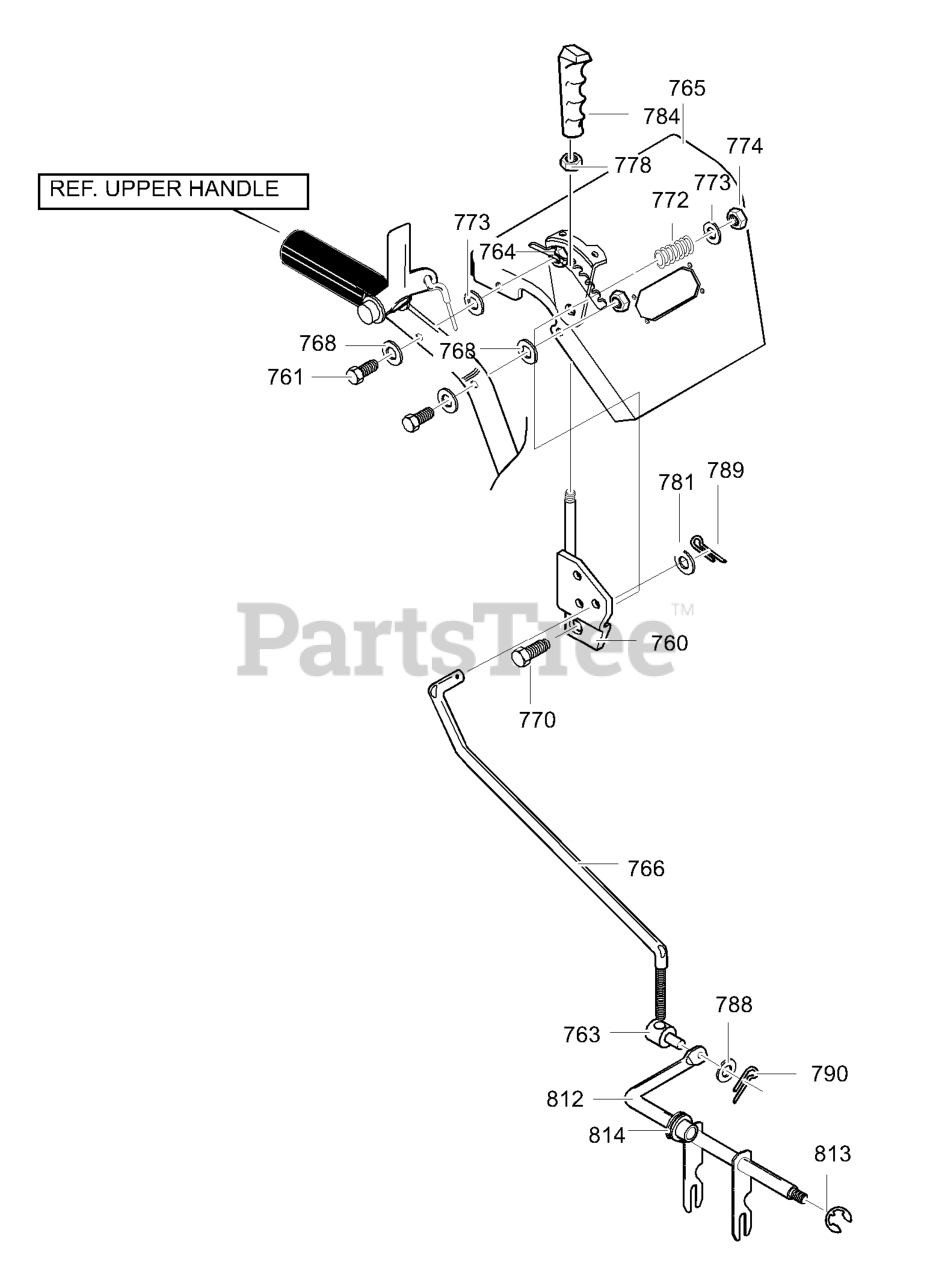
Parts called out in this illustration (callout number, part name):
760	HANDLE ASSY SPD CTRL
761	SCREW, 5/16-18 x 1.75
763	NUT, TRUNNION
764	NUT, 5/16-18 HEXWDFLLK
765	ASSEMBLY, PANEL
766	ROD, SPEED CONTROL
770	SCREW 3/8-16X2.00
773	FLATWASHER
774	NUT, 3/8-16 HEXNYL
778	NUT, 3/8-16 REGHEX
781	FLATWASHER
784	HANDLE 3/8-16
788	FLATWASHER
789	PIN, COTTER
790	COTTER PIN
812	ROD, ASSY YOKE
813	RING, RETAINER
814	BEARING, FLANGE
